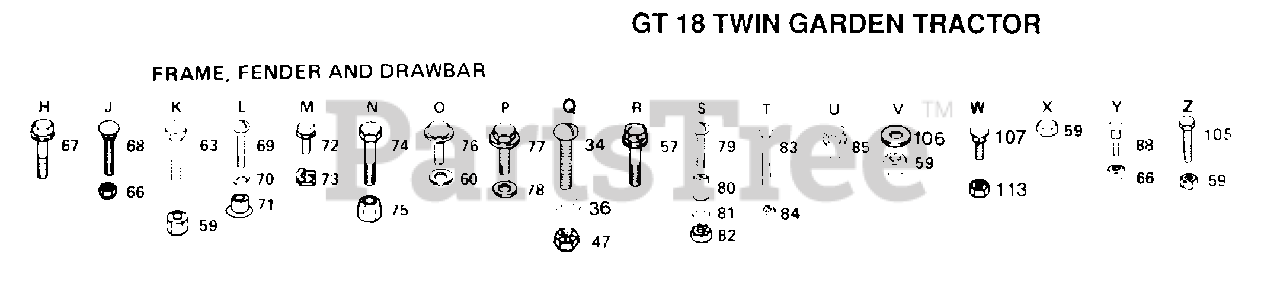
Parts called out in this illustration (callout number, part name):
34	SCREW
36	WASHER
57	SCREW
60	WASHER PM
63	BOLT
68	BOLT
69	SCREW
70	LOCKWASHER
71	WELDNUT
73	"""J"" FASTENER LT"
74	BOLT T
76	SCREW
77	SCREW
78	WASHER
79	SCREW
80	SPACER LT
81	WASHER
83	BOLT
84	NUT GTV
85	SCREW LT
106	WASHER
107	BOLT
113	NUT T
